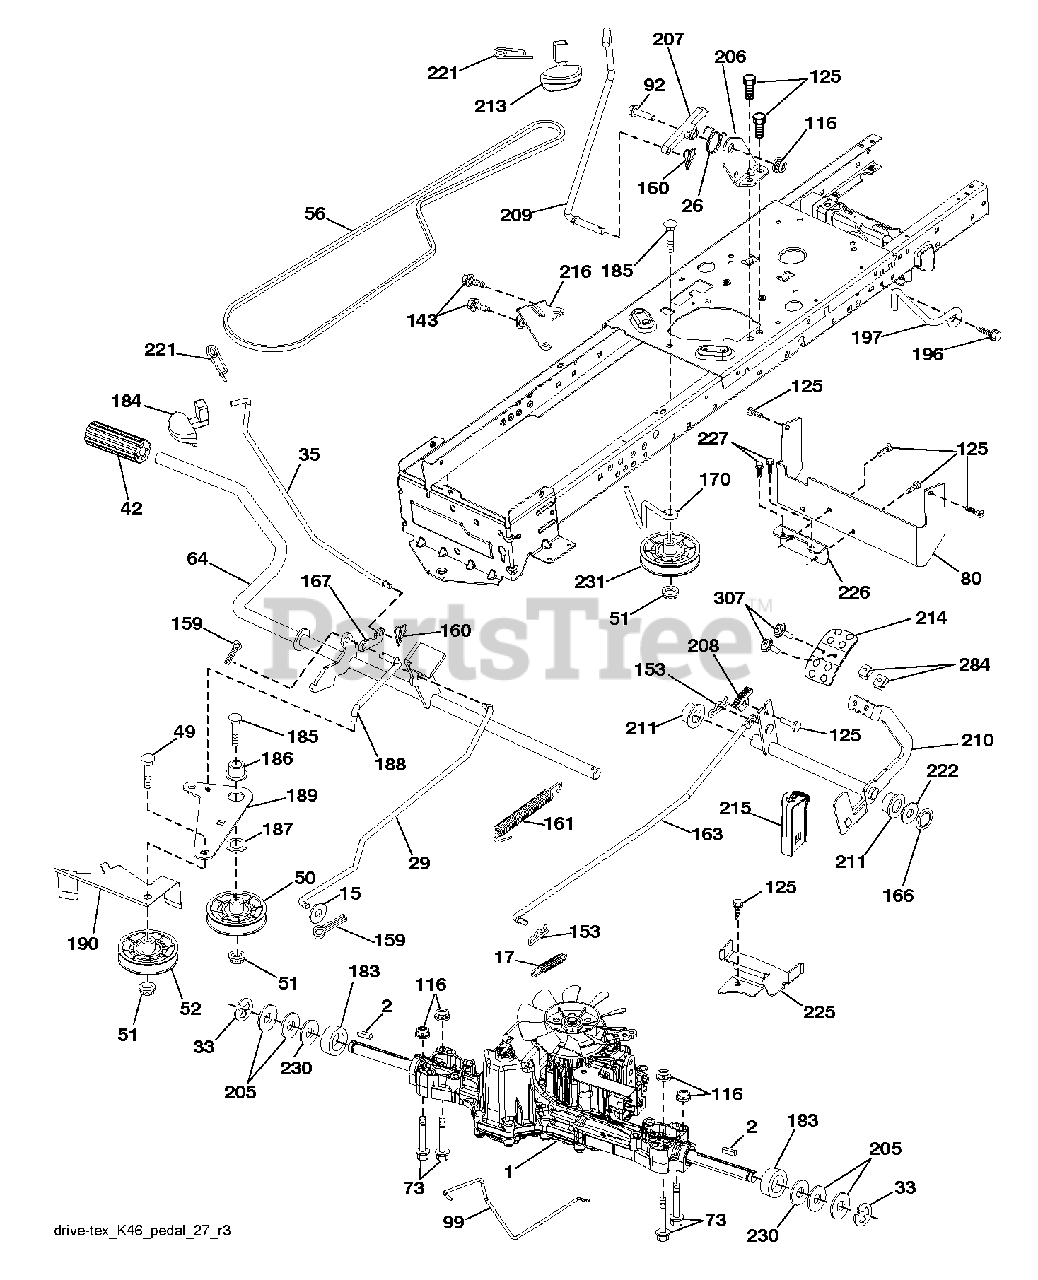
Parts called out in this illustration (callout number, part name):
2	SQUARE KEY
15	WASHER
17	SPRING.BRAKE.K46.GREEN
26	SPRING.RETURN.CRUISE
29	ROD.BRAKE.K46
35	ROD .BRAKE. PARKING. GT. HUSQ.
42	PEDAL COVER T
50	IDLER.FLAT.910.OFFSET
51	NUT LOCK FLG 3/8-16 UNC
52	IDLER.V-GROOVE.910.OFFSET
56	V-BELT.MOWER.92.40.42/K46
64	SHAFT.ASM.PEDAL.BRK.CNTR
80	STRAP.TORQUE.K46.K57R.TT
92	BOLT
99	ROD.SPRING.BYPASS.K46.LT.Z
116	NUT LOCK HEX FLANGE 5/16-18
125	SCREW
143	SCREW LT
153	RETAINER M
159	COTTER PIN
160	RETAINER CLIP
161	SPRING, RETURN LT
163	ROD.CONTROL.K57R.K46
166	NUT.PUSH.625
167	LATCH.BRAKE.SPRING
170	KEEPER.CENTER SPAN.1.688
183	SPACER AXLE
184	RB HANDLE.PARKG.BRK.HUS/PRED
186	SPACER.RETAINER
187	WASHER 12/32X2X10GA
188	RP LINK.CLUTCH.GROUND.DRIVE
189	BELLCRANK.GROUND.DRIVE.TEX.
190	KEEPER.BELLCRANK.DRIVE
196	SCREW 3/8-16X1
197	LINK.CLUTCH.ANIT-ROTAT
206	BRKT.MOUNT.LATCH.CRUIS
207	LATCH.CONTROL.CRUISE
208	GEAR.SECTOR.CONTROL.CR
209	ROD.CONTROL.CRUISE.GT.
210	ROCKER.ASM.PEDAL.CONTR
211	BEARING.NYLON
213	KNOB.CONTROL.CRUSIE.HU
214	PEDAL.FORWARD.HUSQVARNA.DEALER
215	PEDAL.REVERSE.TEX.GT.4
216	BRACKET.PULLEY.IDLER.W/TEX
221	RETAINER.SPRING.CLIP.H
222	WASHER 21/32 X 1-1/4 X 10 GA.
225	KEEPER.BELT.TRANSAXLE.K46
226	BRACKET.MOUNT.TORQUE.K46.TLT
227	SCREW
230	WASHER.HARDENED
231	IDLER.V-GROOVE.1.688.OFFSET
284	NUT.U-CHNL.1/4-20.550DP.350PNL
307	SCREW.MACHINE.CR.1/4-20
